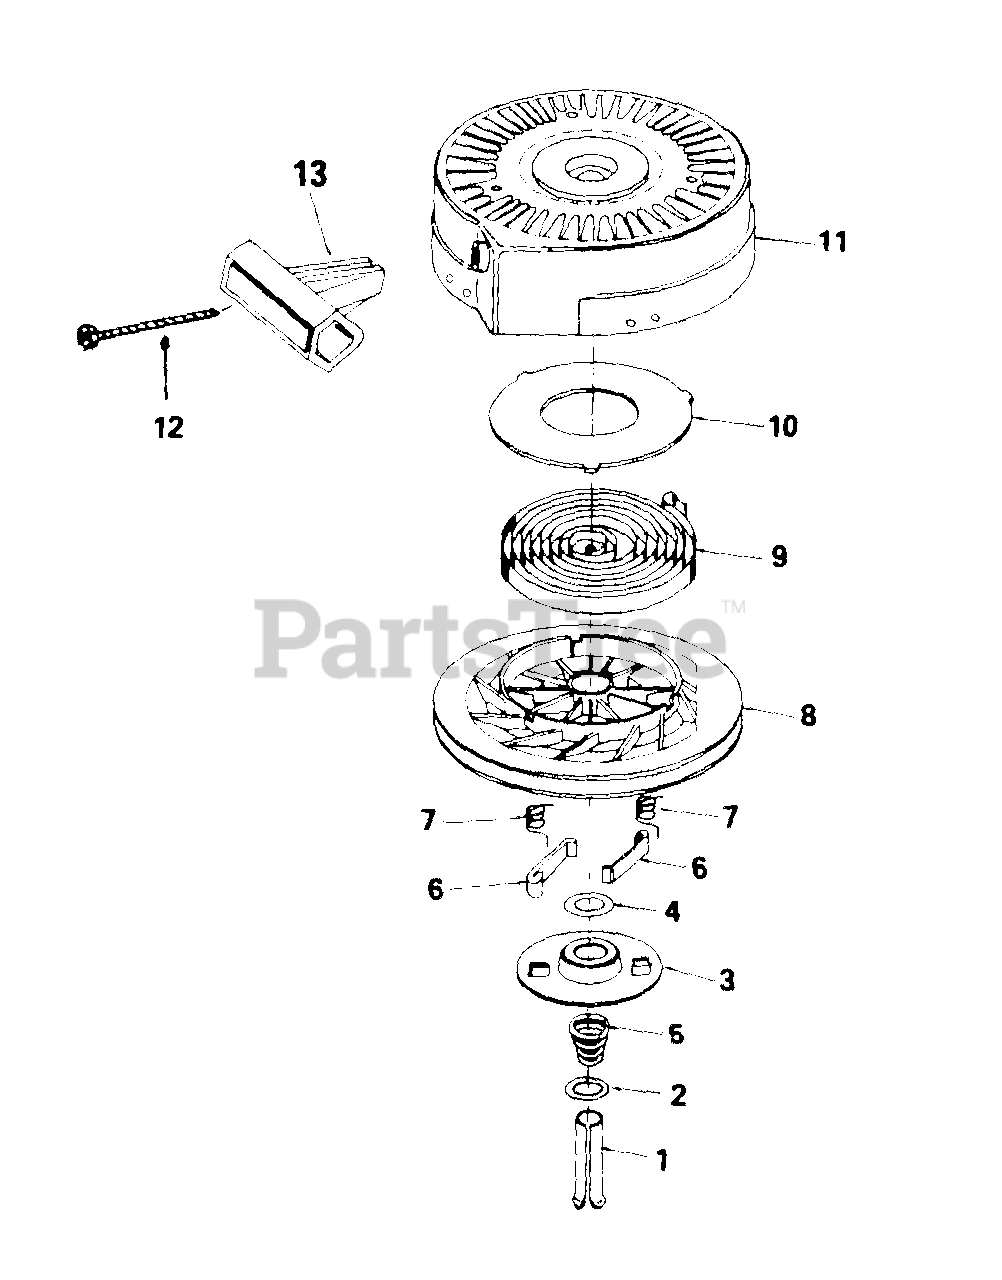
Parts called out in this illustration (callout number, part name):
1	Pin, Spring
5	Spring, Brake
6	Dog, Starter
7	Spring, Dog
8	Pulley
9	Spring, Rewind
10	Cover, Spring
11	Housing Ass'y., Starter
12	Rope, Starter (Length 98" & 9/64" Dia.)
13	Handle, Starter
